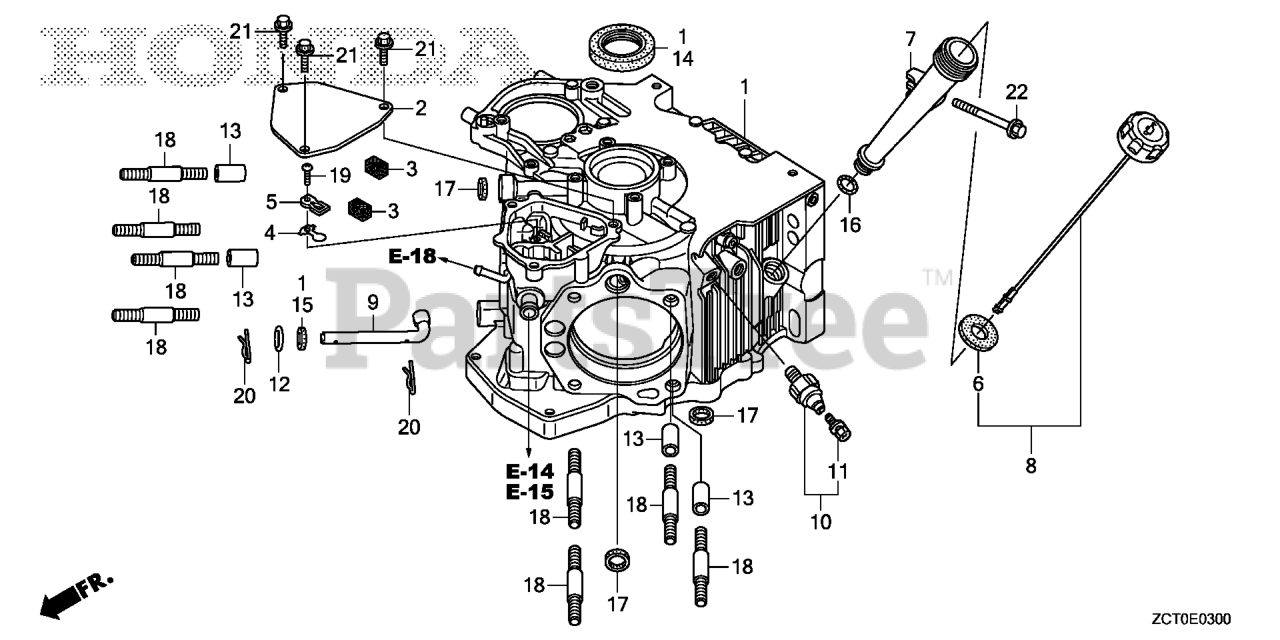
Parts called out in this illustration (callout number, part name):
1	CRANKCASE ASSY.
2	COVER, BREATHER
3	FILTER, BREATHER
4	VALVE, OIL OUTLET
5	PLATE, STOPPER
6	GASKET, OIL FILLER CAP
7	EXTENSION, OIL FILLER
8	GAUGE ASSY., OIL LEVEL
9	SHAFT, GOVERNOR ARM
10	SWITCH, OIL PRESSURE
11	SCREW-WASHER (4X8)
12	WASHER, PLAIN (10MM)
13	PIN, DOWEL (12X20)
14	OIL SEAL (38X58X9)
15	OIL SEAL (10X16X5)
16	O-RING (14.8X2.4)
17	GASKET, OIL PASSAGE
18	BOLT, STUD (10X40)
19	SCREW, PAN (3X8)
20	PIN, LOCK (10MM)
21	BOLT, FLANGE (6X14)
22	BOLT, FLANGE (6X45)
